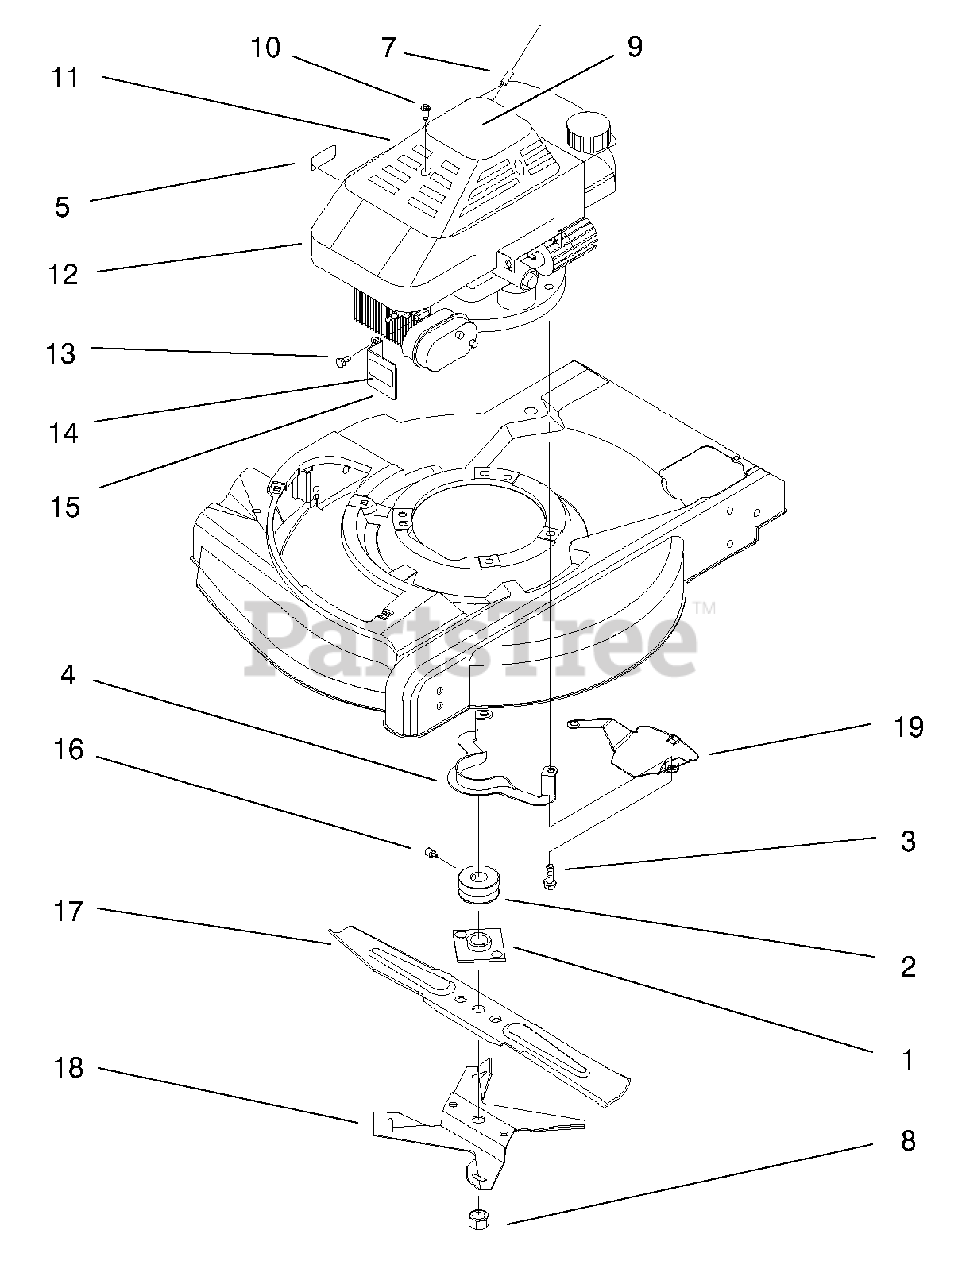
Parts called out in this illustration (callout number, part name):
1	Plate & Collar ASM
3	Screw-Taptite w/Patch
4	Guide-Belt
5	Decal-Oil Instr.
7	Rope-Stop
8	Nut-Blade
9	Decal-Recoil
10	Screw-Recoil Cover
11	Cover-Starter
12	Shroud-Engine
14	Decal-Surface, Hot
15	Guard-Muffler
15	ASM-Muffler Guard
16	Screw-Set,Cone Point
17	Blade
18	Fan-Mulching
19	Shield-Grass
